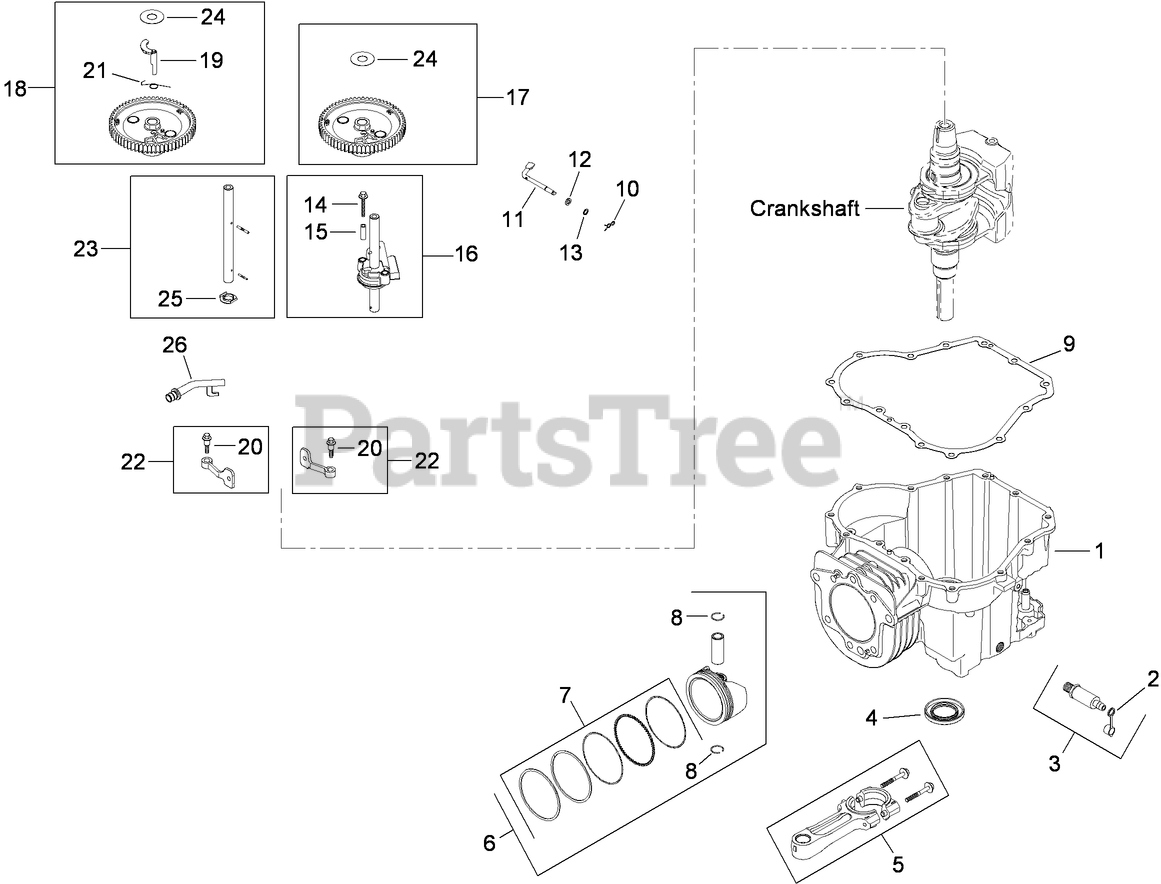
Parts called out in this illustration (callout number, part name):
1	SV610/620 SHORT BLOCK
2	CAP-VALVE, OIL DRAIN
3	OIL DRAIN VALVE ASM (INCLUDES 3)
4	Seal-Oil
5	CONNECTING ROD ASM
6	PISTON W/RING SET (94MM) (INCLUDES REF 5, 6)
7	RING SET (94MM)
8	RETAINER-PIN, PISTON
9	Gasket-Plate, Closure
10	Clip-Pin, Hitch
11	Shaft-Cross, Governor
12	WASHER-FLAT (6mm)
13	WASHER-FLAT (1/4)
14	Screw-Pump, Oil
15	Spacer-Screw, Oil Pump
16	Oil Pump ASM (Includes 17-18)
17	CAM GEAR ASM (INTAKE)
18	CAM GEAR ASM (EXHAUST) (INCLUDES REF 19, 21, 24)
19	WEIGHT-ACR
20	Bolt-Shoulder (M6x1x26)
21	Spring-A C R
22	Cam Lever ASM (Includes 22)
23	CAMSHAFT CENTER ASM (EXHAUST) (INCLUDES REF 19)
24	Washer-Thrust, A C R
25	WASHER-THRUST
26	Tube-Back, Drain
